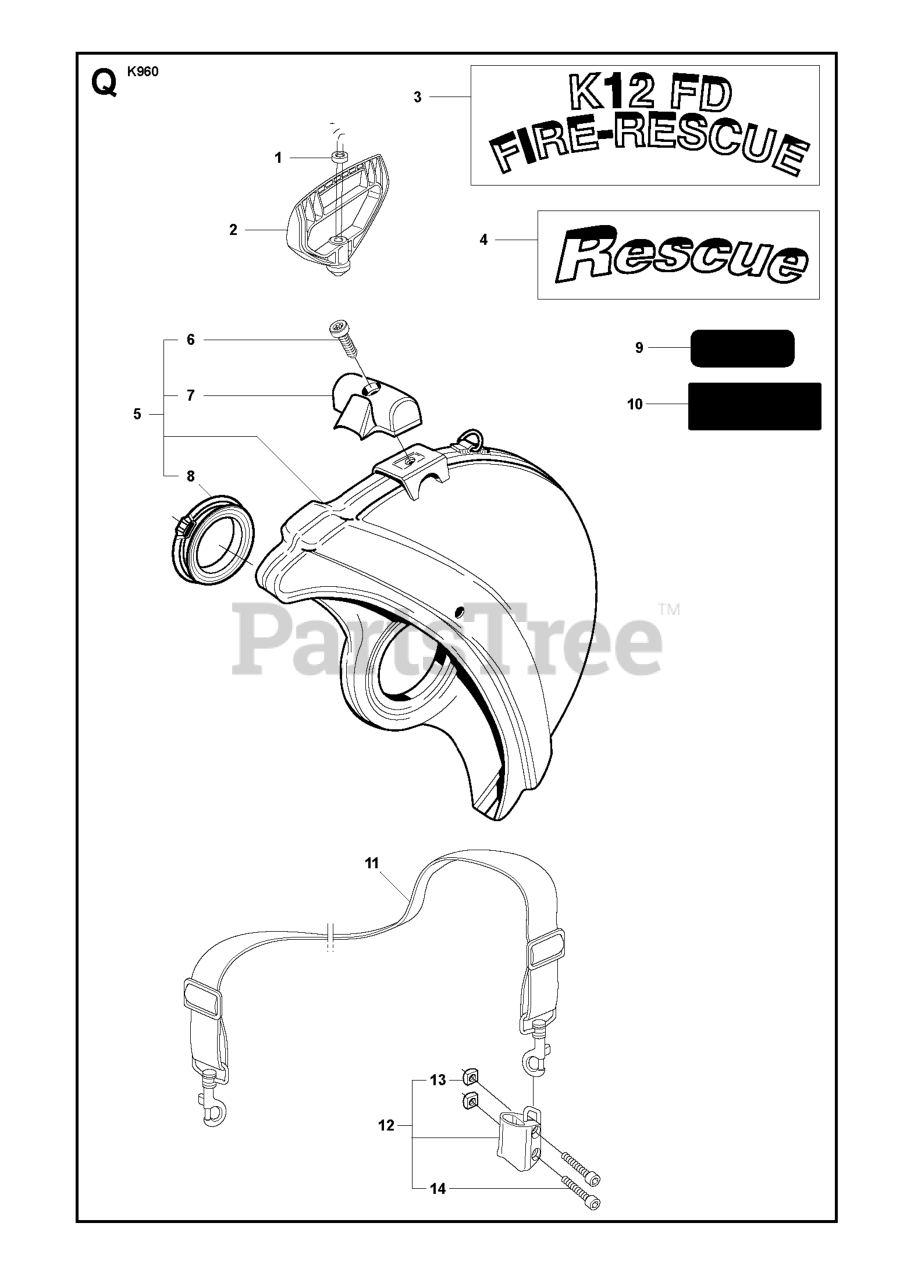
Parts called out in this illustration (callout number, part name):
5	HEEL GUARD ASSY 14" CHROME
5	WHEEL GUAR ASSY 12" CHROME
6	SCREW.
9	LABEL
11	RP HARNESS
12	RP BRACKET
